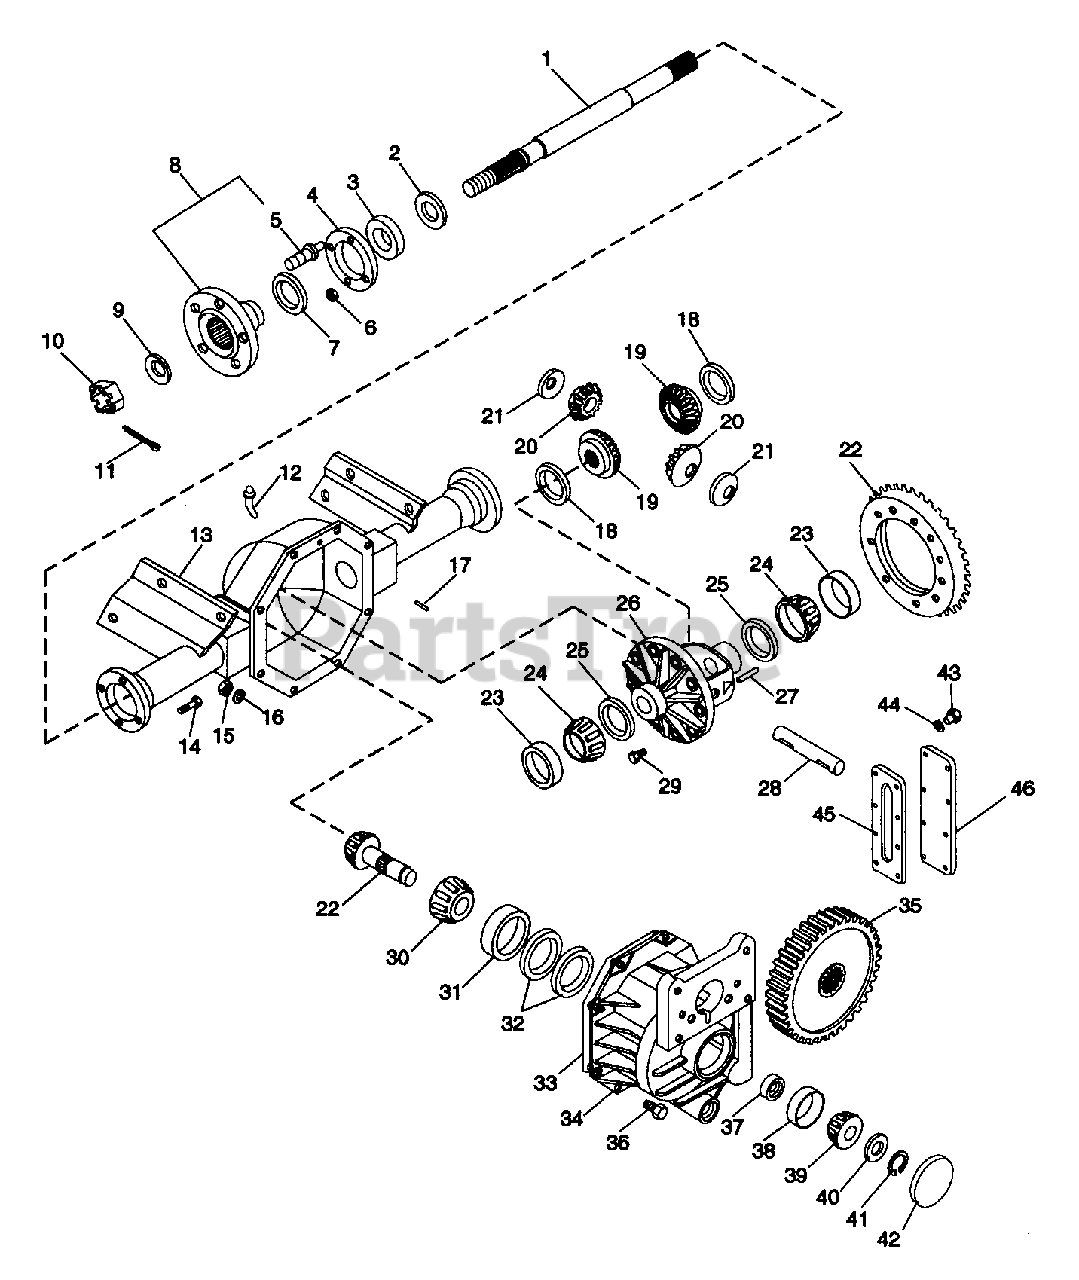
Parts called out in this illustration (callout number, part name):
1	AXLE SHAFT LH
1	AXLE SHAFT RH
2	SEAL 1.183X1.183X.265
3	BRG-CONE 46MMX17MM
4	GASKET-SEE LETTER L-307
5	CARRIER LUG BOLT
6	NUT-LK-FLG .312-24 GR C
7	FELT SEAL
8	AXLE FLANGE ASSEMBLY
9	WSHR-FL-STL .875X1.500X.1196
10	NUT-SL .875-14
11	PIN-COTR .15X1.50
13	LOWER HOUSING
14	BLT-HEX .31-24X1.25 GR8
15	NUT-HEX .312-18
16	WSHR-LK-INT .313X.030 PL
17	DOWEL PIN
18	WSHR-FL-STL 1.578X2.375X.031
19	SIDE GEAR
20	BEVEL GEAR
21	WSHR-BLVL .703X1.593X.031
22	PINION & GEAR
23	BRG-CUP 2.892X.580
24	BRG-CONE 1.63X.78
26	DIFFERENTIAL CASE
27	LOCK PIN
28	PINION SHAFT
29	BLT .38-24X.812 DANA
30	BRG-CONE 1.188X.84
31	BRG-CUP 2.532X.656
32	SHIM
33	GASKET
34	FRONT HOUSING W/BRG CAP & SCRE
34	FRONT HOUSING W/BEARING CAP &
35	SPUR GEAR
36	BLT-HEX .31-18X1.00 PL GR5
37	FRONT PINION BEARING SPACER
38	BRG-CUP 1.968X.550
39	BRG-CONE .844X.72
40	SHIM ASSEMBLY
41	RG-RTNG-EXT .813X.042
42	CUP PLUG
43	TAPTITE M5-0.8X16MM H-FL-PL
44	WSHR-LK-EXT 12X.025 PL
46	SIDE COVER
